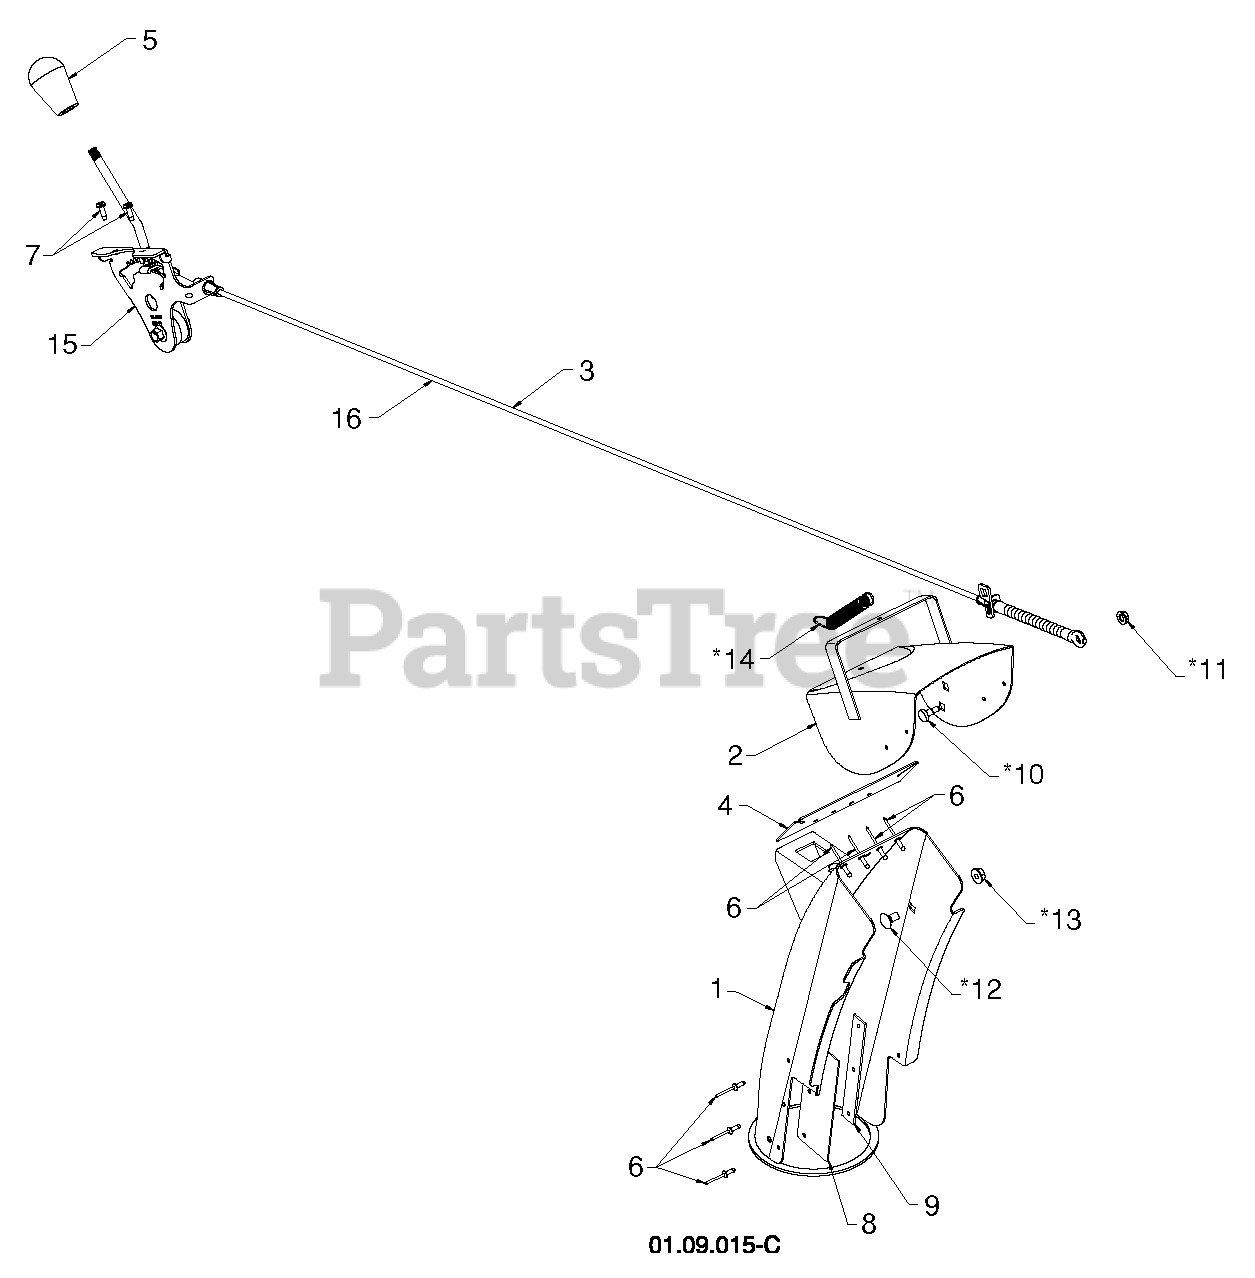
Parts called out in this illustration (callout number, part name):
1	CHUTE.WELDMENT.BLACK
3	CONTROL.ASM.DEFLECTOR.BLACK.SN
4	SEAL.DEFLECTOR
5	KNOB LEVER, BLACK
6	RIVET BLIND
7	SCREW
8	SHIELD.SNOW.CHUTE
9	STRAP.SHEILD.RETAINER
10	BOLT, SHOULDER
11	NUT.HEX.FLANGE.1/4
13	NUT.LOCK.5/16-18
14	SPRING.DEFLECTOR.REM.CHUTE
15	CHUTE.DEFLECTOR.HEAD.SERVICE.
16	CABLE.DEFLECTOR.SNOW
